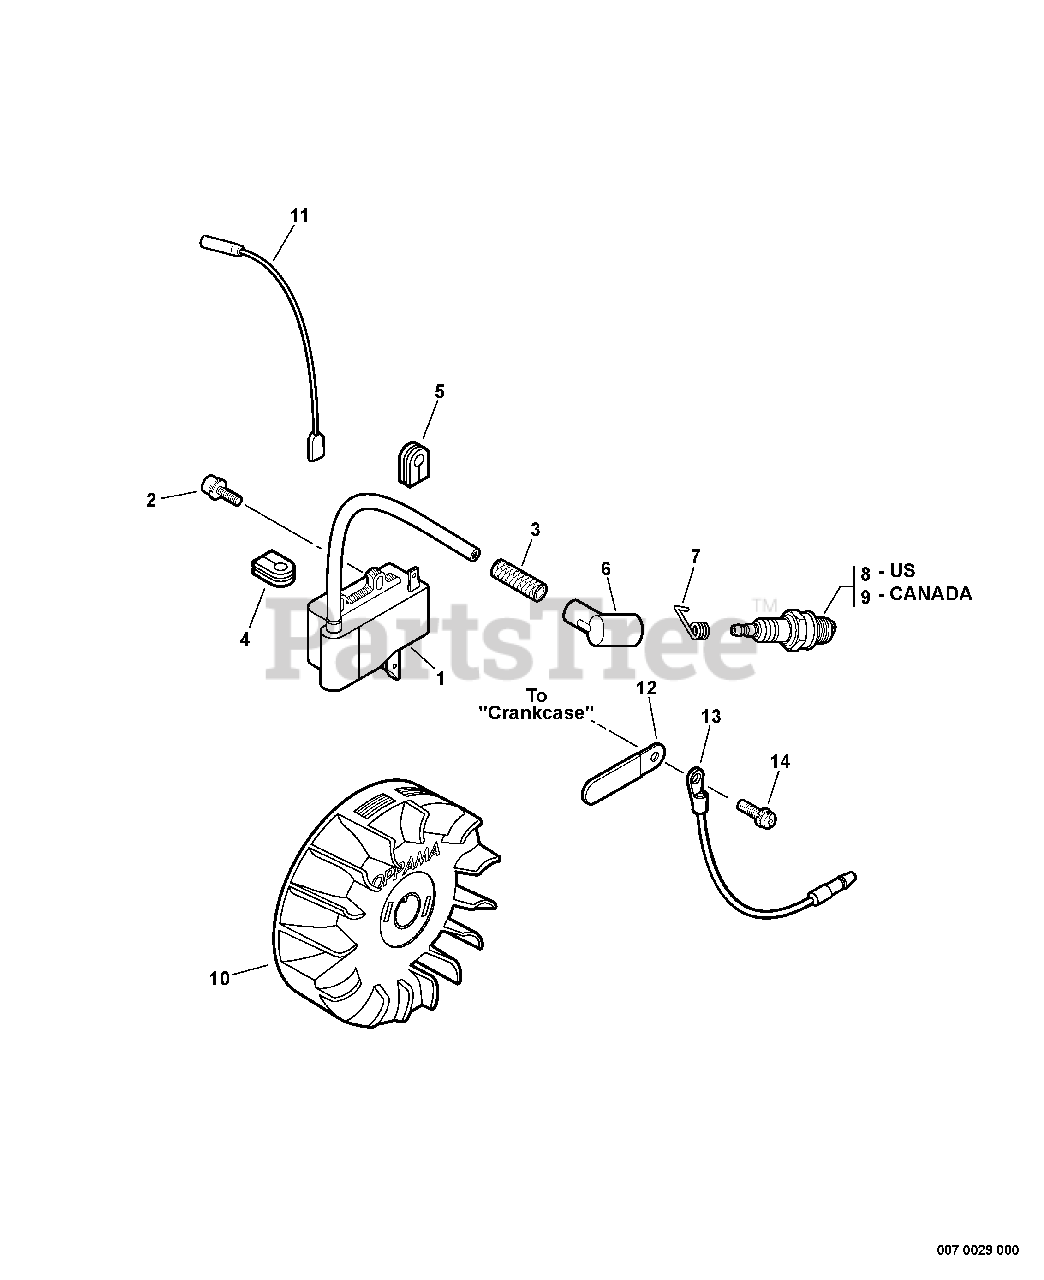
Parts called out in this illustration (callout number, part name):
1	COIL, IGNITION
2	SCREW - 4X20
3	INSULATOR
4	GROMMET
6	CAP, SPARK PLUG
7	TERMINAL, SPARK PLUG CAP
8	SPARK PLUG -- BPM-8Y
9	SPARK PLUG -- BPMR-8Y
10	FLYWHEEL
11	LEAD - IGNITION
13	LEAD - GROUND
14	SCREW - 5X10
